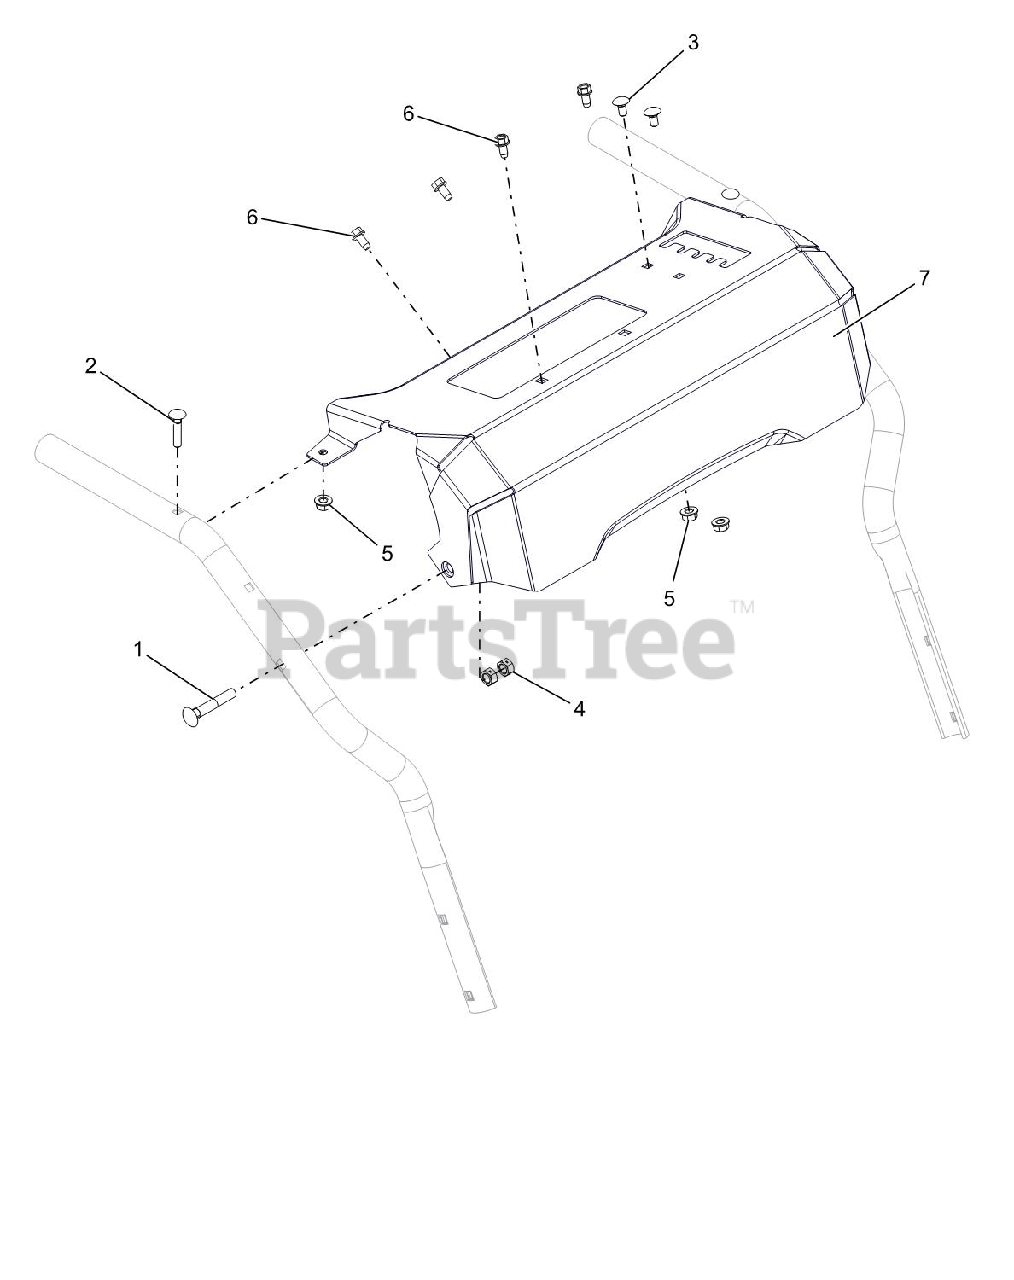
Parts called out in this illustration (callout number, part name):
1	BLT-RDHDXLSQNK .31-18X2.0 G5YZ
2	BLT-RDHDXLSQNK.25-20X1.25 G5ZC
3	@BLT-RDHDSQNK .25-20X.50 G5YZ
4	@NUT-LK-CTR .31-18 YWZC
5	@NUT-LK-TOP-FLG .25-20 YWZC
6	SCR-TAP .25-20X.50 HWH TR YWZ
7	CTRL PANEL W/DECAL-SNOTEK REMO
